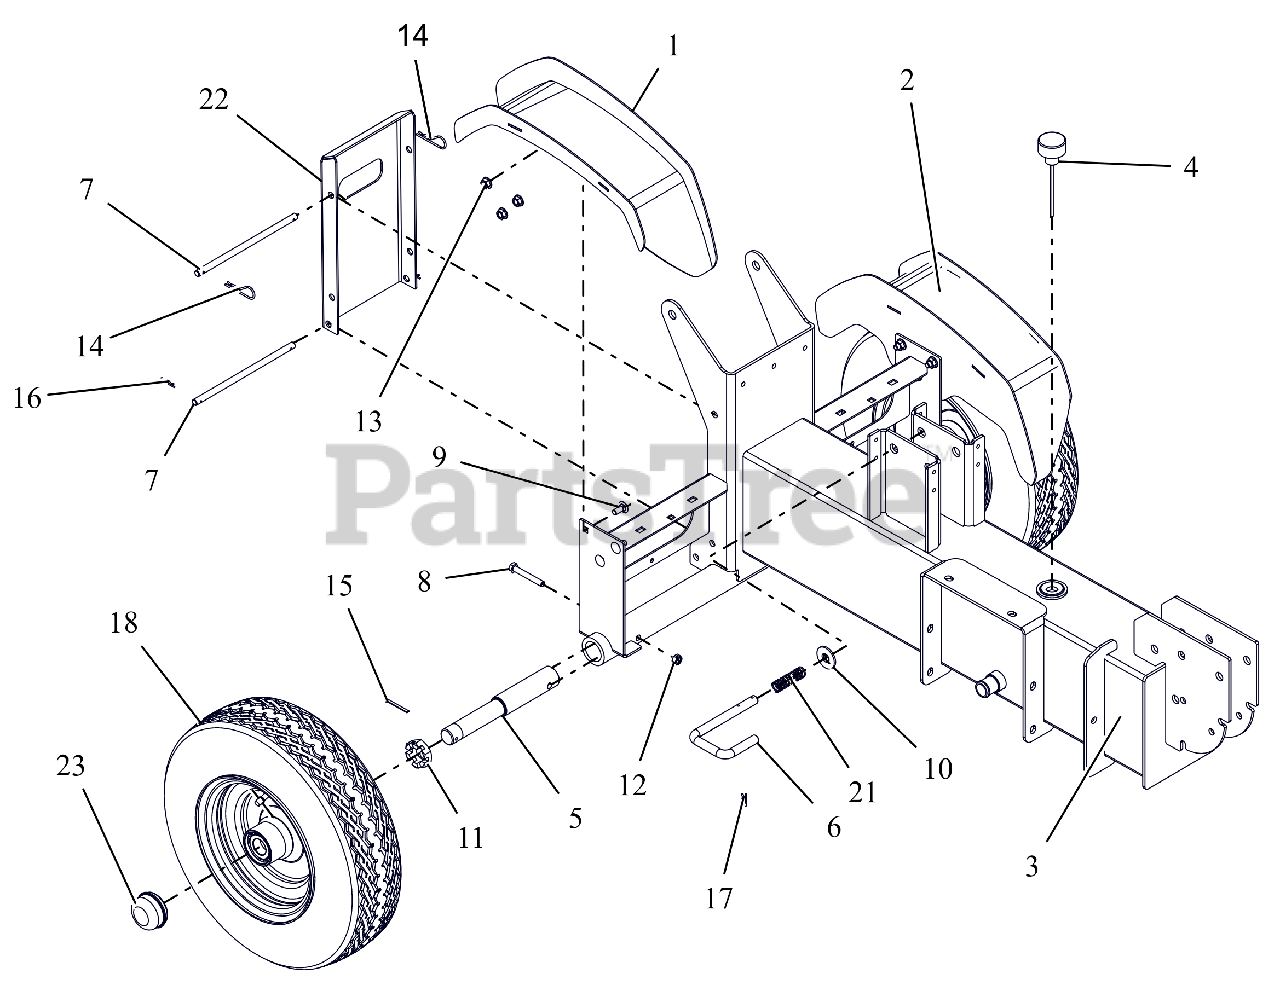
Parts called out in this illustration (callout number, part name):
1	WMT-FENDER-RH
2	WMT-FENDER-LH
3	CHASSIS-SPLITTER W/SFTY DECALS
4	BREATHER, DIPSTICK
5	AXLE, SPLITTER
6	LOCK, BEAM
7	PIN, .373 X 7.30 X 2X.109 THRU
8	@BLT-HEX .31-18X2.25 GR5 YWZC
9	@BLT-RDHDSQNK .31-18X.75 G5YZ
10	@WSHR-FL-STL.563X1.38X.109YWZC
11	NUT-SL 1.0-14
12	@NUT-LK-CTR .31-18 YWZC
13	@NUT-LK-TOP-FLG .31-18 YWZC
14	HAIRPIN, #7 CLIP .094X2.31 YWZ
15	@PIN-CTR .15X1.50 YWZC
16	PIN-HAIR, ENDRIES #25 YWZC
17	CLIP, SPRING
18	ASM,TIRE/WHEEL 4.8/4-8 P47GRAY
21	SPRG, COMP .058X.65X2.13 WLD15
22	REAR STAND W/DECALS (ARIENS)
23	CAP, DUST
